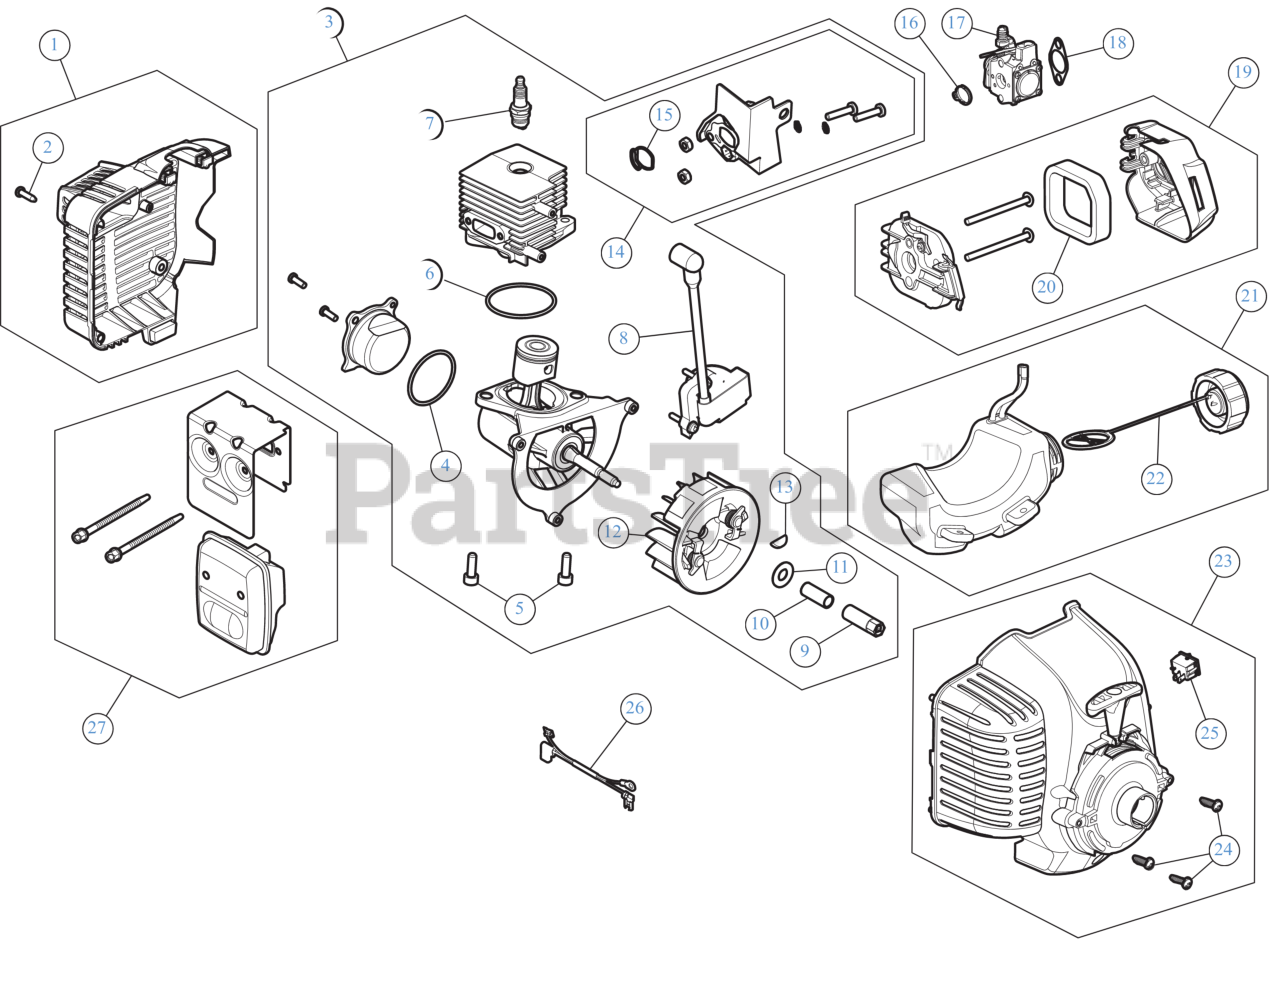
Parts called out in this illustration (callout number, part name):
1	HOUSING ASSEMBLY RR
2	SCREW 8-16 x 3/4
3	SHORT BLOCK
4	O-RING SEAL CRANKCASE
5	SCREW 5/16-18x3/4 T40
6	O-RING SEAL CYLINDER
7	SPARK PLUG
8	MODULE ASSEMBLY
9	POWER SHAFT ADAPTER
10	SPACER CRANKSHAFT
11	BELL WASHER
12	FLYWHEEL ASSEMBLY
13	WOODRUFF KEY #403-.125 x .375
14	INTAKE ASSEMBLY
15	INSL/CYL SEAL
16	CARBURETOR SEAL
17	CARBURETOR
18	GASKET CARB
19	AIR CLEANER
20	AIR FLITER
21	FUEL TANK ASSEMBLY
22	FUEL CAP ASSEMBLY
23	STARTER HOUSING
24	SCREW #
25	SW, MOMENTARY ON/O
26	SHORT WIRE LEAD
27	MUFFLER ASSEMBLY
